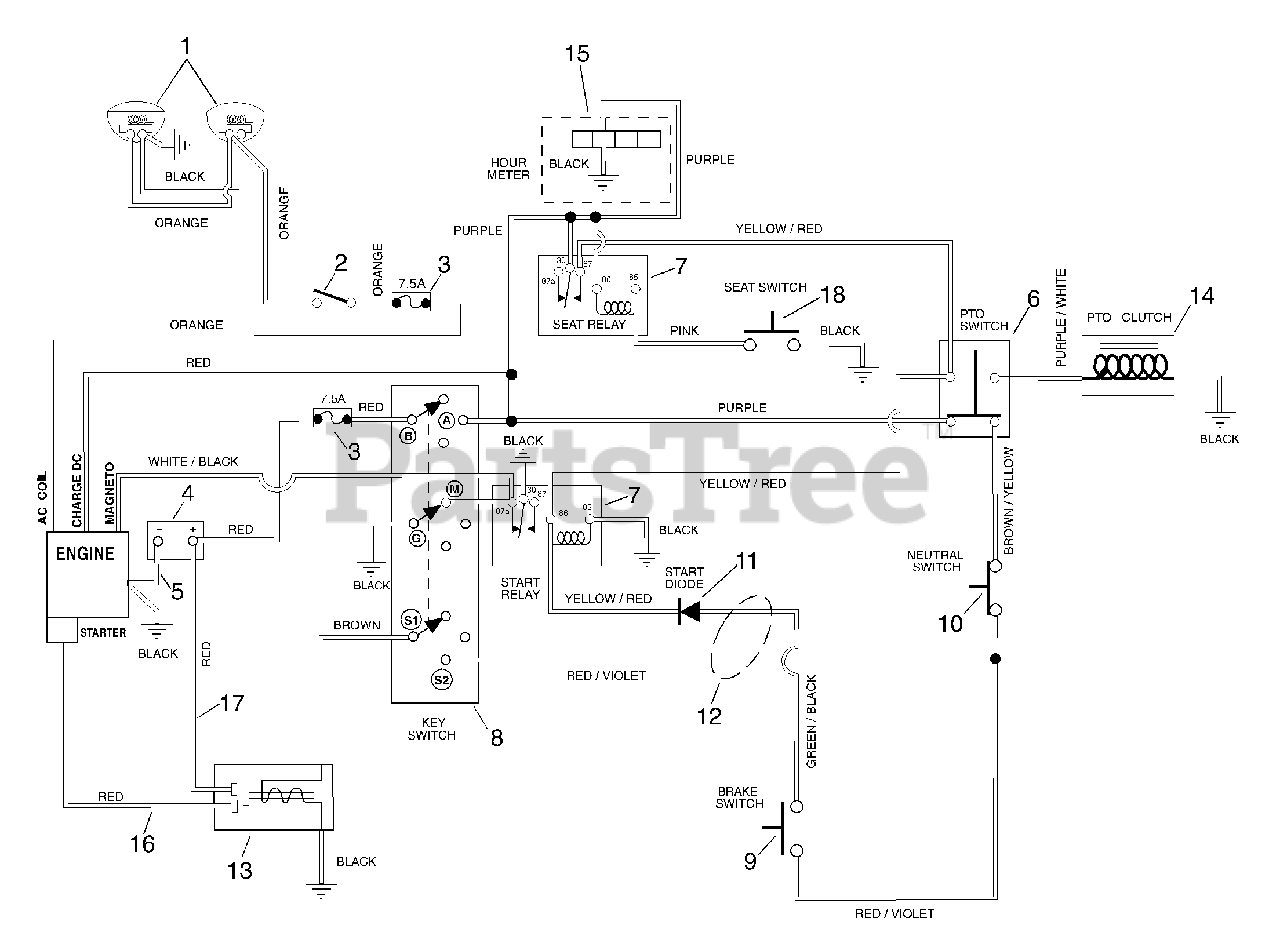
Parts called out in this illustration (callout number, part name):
1	HEADLIGHT- RH
2	SWITCH - LIGHT
3	7.5 AMP Fuse
4	BATTERY W/TUBE
5	GROUND CABLE .31X22.00X.31
6	PTO KNOB/ SWITCH ASSY
7	RELAY
8	KEY SWITCH
9	SWITCH, NEUTRAL START N.C.
10	SWITCH- SINGLE POLE N.O.
11	MOLDED DIODE PLUG 1 AMP
12	HARNESS, WIRING - 1340 G
13	SOLENOID
14	ELECTRIC CLUTCH/BRAKE(1.8AMP)
15	HOURMETER KIT- SIERRA
16	START CABLE 22"
17	STARTER CABLE 6.75"
18	SWITCH- SEAT
